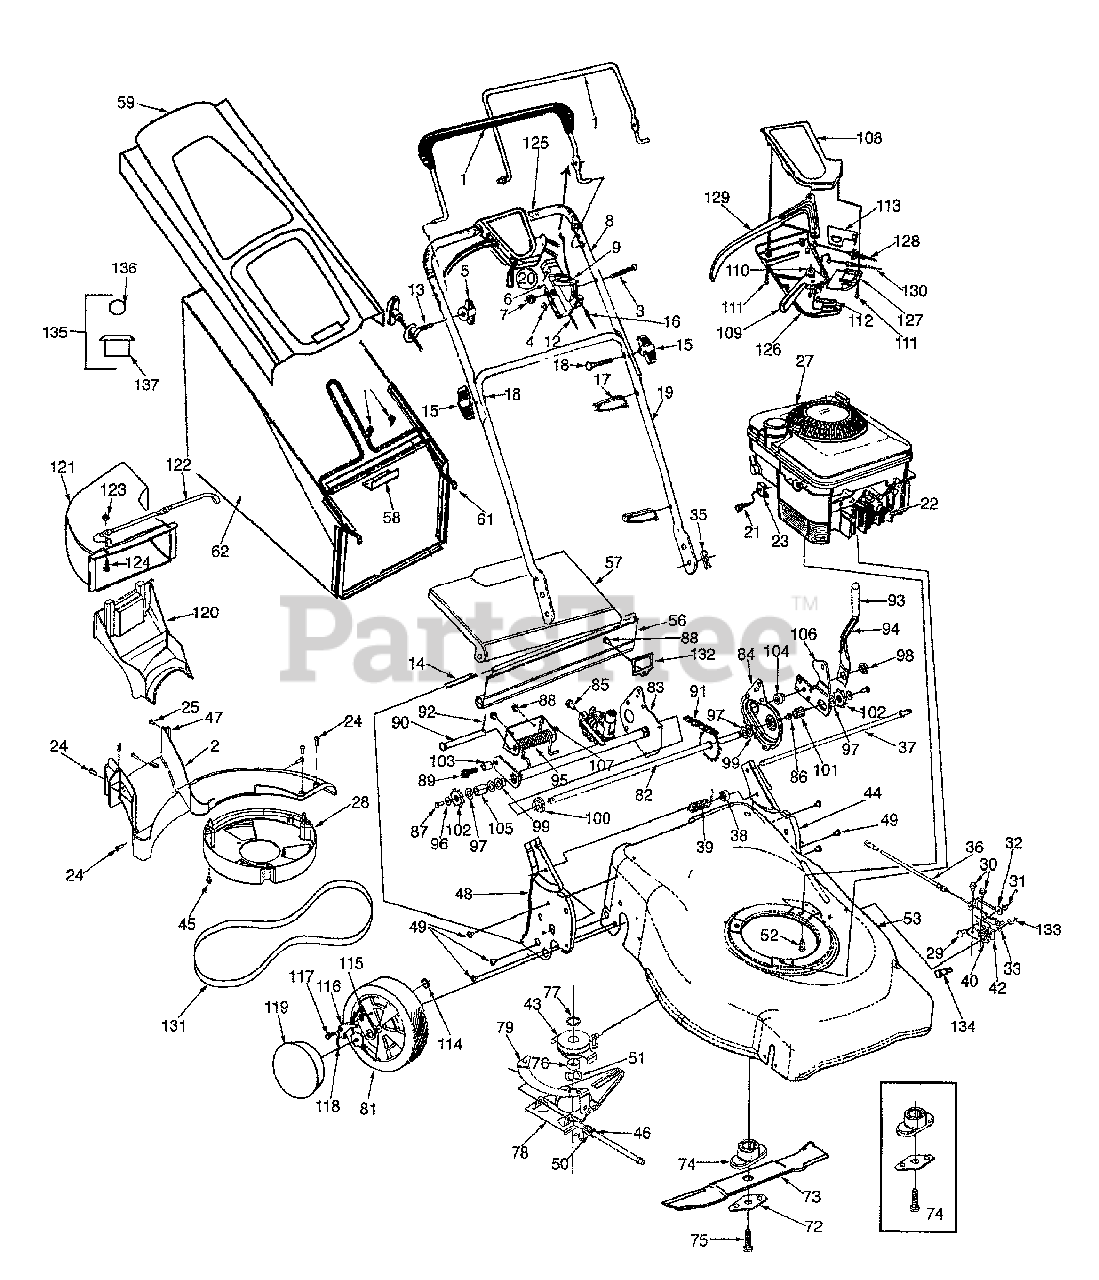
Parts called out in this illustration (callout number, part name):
2	Baffle
3	Oval C-Sunk Mach - Screw
4	Spring Washer .66" ID
5	Handle Knob 1/4-20 Thd.
6	Throttle Housing
7	Hex L-Nut 1/4-20
9	Throttle Lever
12	Throttle Control Wire-55"
13	Rope Guide
14	Wire-47" Lg.
15	Hand Knob
16	Control Cable-40.5"
17	Cable Tie
18	Curved Hd. Bolt 5/16-18x2" Lg.
20	Throttle Assy Comp
21	Hex Self-Tap Scr. #10-32 x .62" Lg. (B&S)
22	Spark Plug Boot
23	Cable Clamp (B&S)
24	Screw H.L. 12-24
25	Screw Mach. B Tapp.
27	Engine
28	Belt Cover
29	Scr. 1/4-20: .50 Lg.
30	Scr.:AB 1/4-20: .625 Lg.
31	Hex Nut: 1/4-20
32	Bell Wash. .265 x .75 x .062
33	Lock Wash. 1/4
35	Int. Cotter Pin 5/15" Dia.
37	Pivot Rod
38	Shoulder Spacer
39	Torsion Spring L.H.
40	Roller Cable
46	Pivot Shaft
47	U-Nut
50	Torsion Spring
51	Wv.Wash.1.38 O.D. x .88 I.D:.029
52	Hx L-Wash Hd. Scr. 3/8-16 : 1" Lg.
53	21" Deck Ass'y w/Icon
56	Rear Flap 17.77 Lg.
62	Grass Bag - Black
72	Blade Bell Support
73	21" Mulching Blade w/Star
74	Blade Adaptor Kit w/Star
75	Hex Bolt 3/8-24 x 2.5 Lg.
76	Spacer - Sleeve
77	Spacer - Sleeve
81	Wheel Assembly
82	Axle Ass'y: RR
86	Scr. TT 1/4-20
87	Hx Cap Screw 1/4-20
88	Scr. AB 1/4-20
89	Scr 3/8-16 x 1.25
90	Pin - Clv. .500 Dia. x .4.62 Lg.
91	Chain: Endless 48:.500P x 22L
92	Pin-Cotter. 125 O.D. x .75
93	Grip-Foam
94	Spring Lever
95	Torsn Spring
96	Bell Washer.265 x .75 x .062
97	Wash.-Fl.508 I.D. x 1.0 O.D. x.020
98	Nut- Shoulder .625 x .165Lg.
99	Bearing-Flg Hex
100	Bearing-Flg. Hex
101	Bearing-Sleeve
102	Rachet Wheel
103	Spacer - .385 x .625 x .700
104	Spacer-Shoulder .385 I.D.x .715Lg.
105	Spacer Sleeve .520 I.D. x .950 Lg.
109	6 Speed Shift Lever
110	Gear Insert
111	C-Sunk Tap Scr. #10 x .75" Lg.
112	Shift Lever Spring
113	6 Sp. Rack Cable Bracket
114	Weld Top L. 1/4-20
115	Pawl Plate
116	Pawl R.H.
117	Shldr. Scr. .340 x .285
118	Spring, Rachet
119	Hub Cap
120	Mulch Plug
121	Chute Deflector
122	Chute Mounting Rod
123	Hex-L-Nut 1/4-20 thd.
124	Mach. Scr. 1/4-20
125	Foam Grip
126	Lower Control Housing
127	Cable Mounting Cap
128	S. P. Cable
129	Control Lever
130	6 Speed Cable - 53" Lg.
131	Belt
134	Sh. Scr. 1/4-28:.375 Lg.
